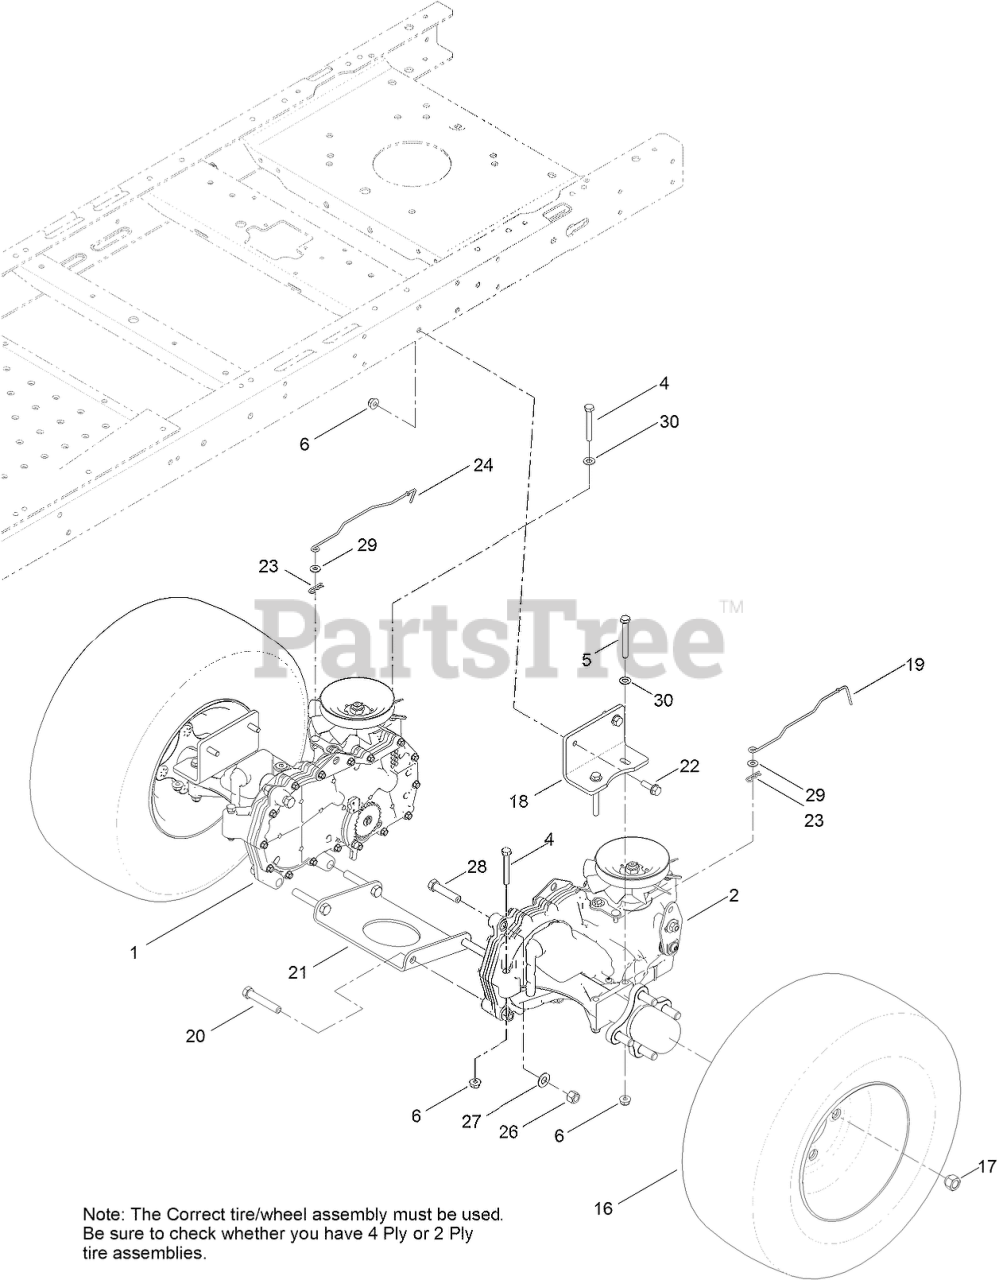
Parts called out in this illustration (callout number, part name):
1	RH HYDRO TRANSAXLE ASM
2	LH HYDRO TRANSAXLE ASM
4	SCREW-HH
5	SCREW-HH
6	NUT-HF, NI
16	4 PLY WHEEL AND TIRE ASM
16	2 PLY TIRE AND WHEEL ASM
17	NUT-LUG
18	MOUNT-HYDRO
19	ROD-BYPASS, LH
20	SCREW-HH
21	PLATE-CROSS, HYDRO
22	SCREW-HHF
23	PIN-COTTER
24	ROD-BYPASS, RH
26	NUT-LOCK, NI
27	WASHER-FLAT
28	SCREW-HH
29	WASHER
30	WASHER-PLAIN
